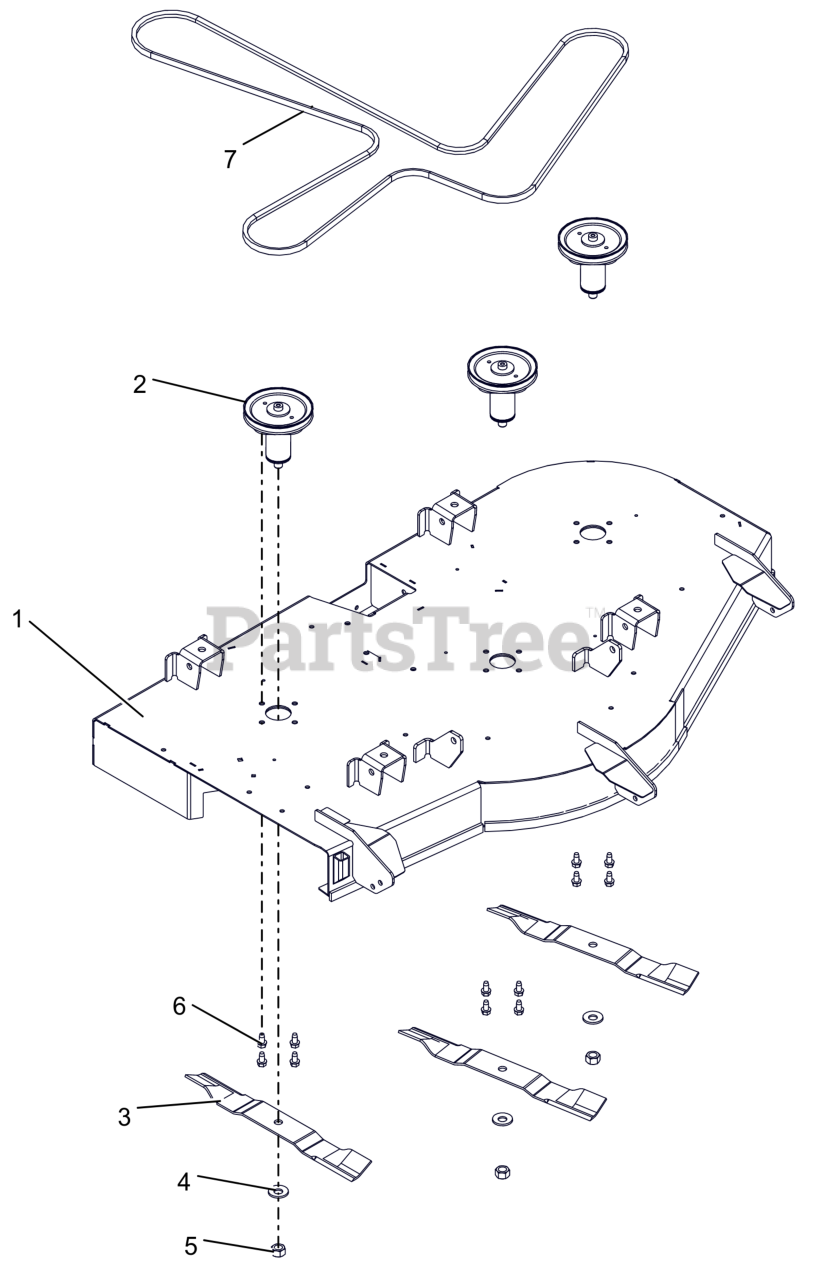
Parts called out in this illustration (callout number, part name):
1	KIT, 52" GRAVELY DECK W/DECALS
2	KIT, DECK SPINDLE ASM-52
3	BLADE, 18" - 30 DEG .5 OFFSET
4	WSHR-BLVL .669X1.535X.138
5	NUT-STD .625-18 ZCC
6	SCR,TAP .375-16X.75 HWH TR ZCC
7	V-BELT, HA-WRAPPED
